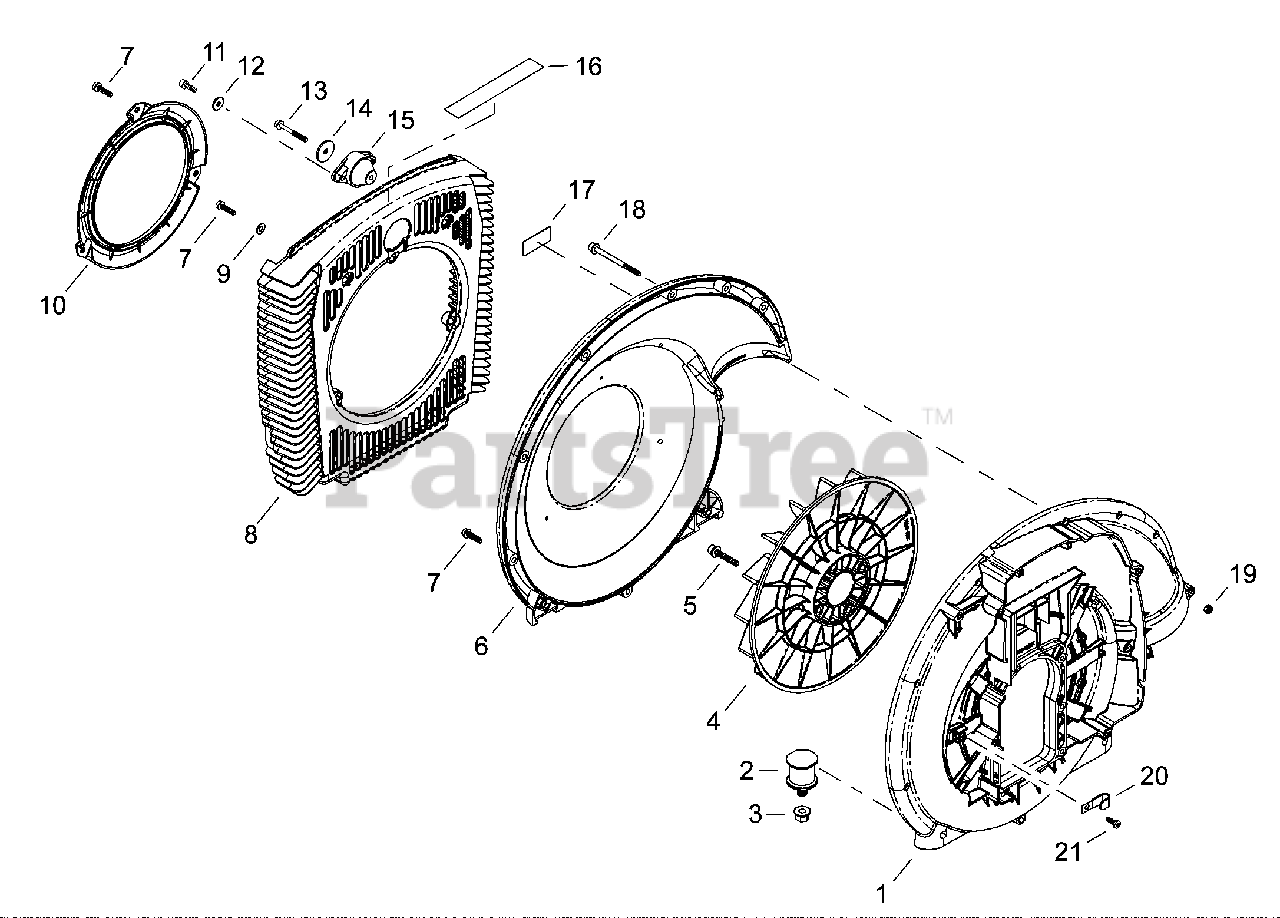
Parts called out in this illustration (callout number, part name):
1	CASE, FAN
2	CUSHION, AV 6
3	NUT, FLANGE M6
4	FAN
5	BOLT M6×35
6	COVER, FAN
7	BOLT M5×20
8	GUARD, DEBRIS
9	WASHER 5 MM
10	COVER, DEBRIS GUARD
11	BOLT M5×16
12	WASHER Ø15ר5.2×1.6
13	BOLT TAPPING M5
14	WASHER Ø25ר5.5×2
15	CUSHION, AV 5
16	LABEL, CAUTION
17	LABEL, CAUTION - AIR INTAKE
18	BOLT M5×70
19	NUT M5
20	CLIP
21	SCREW, TAPPING 5×14
